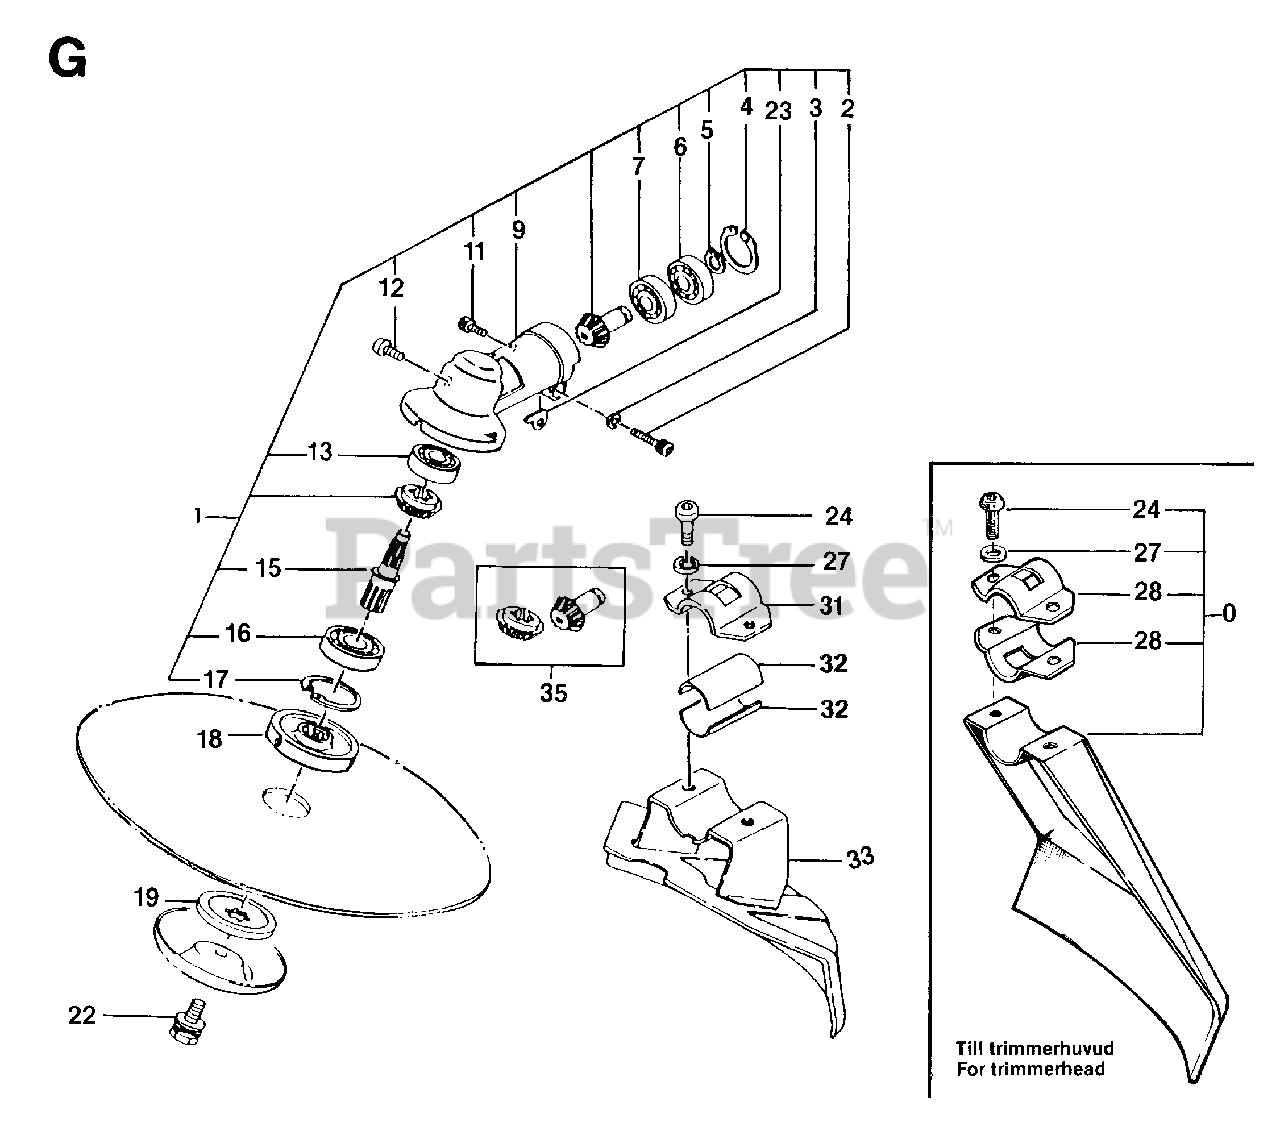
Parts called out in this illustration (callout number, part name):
2	SCREW MC6S 5X25
3	SPRING WASHER
5	RETAINING RING SGA 10
11	SCREW MC6S 5X10
17	RETAINING RING SGH 28
27	SPRING WASHER
